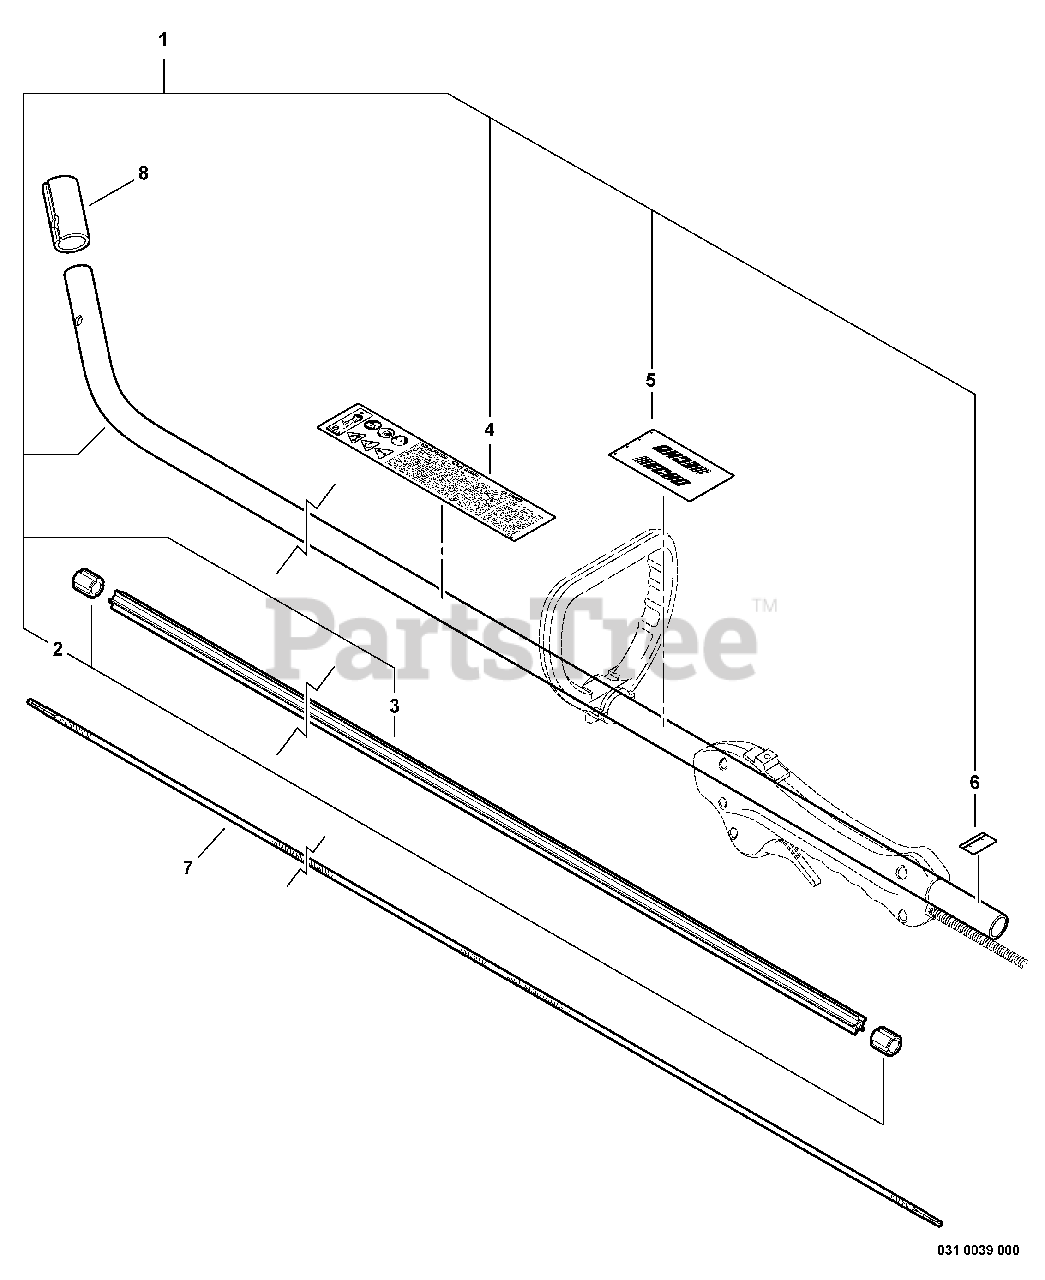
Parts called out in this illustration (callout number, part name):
1	MAIN PIPE ASSY
3	LINER - FLEXIBLE
4	LABEL - CAUTION
5	LABEL - HANDLE LOCATION
6	LABEL - ALIGNMENT
7	DRIVESHAFT - FLEXIBLE
